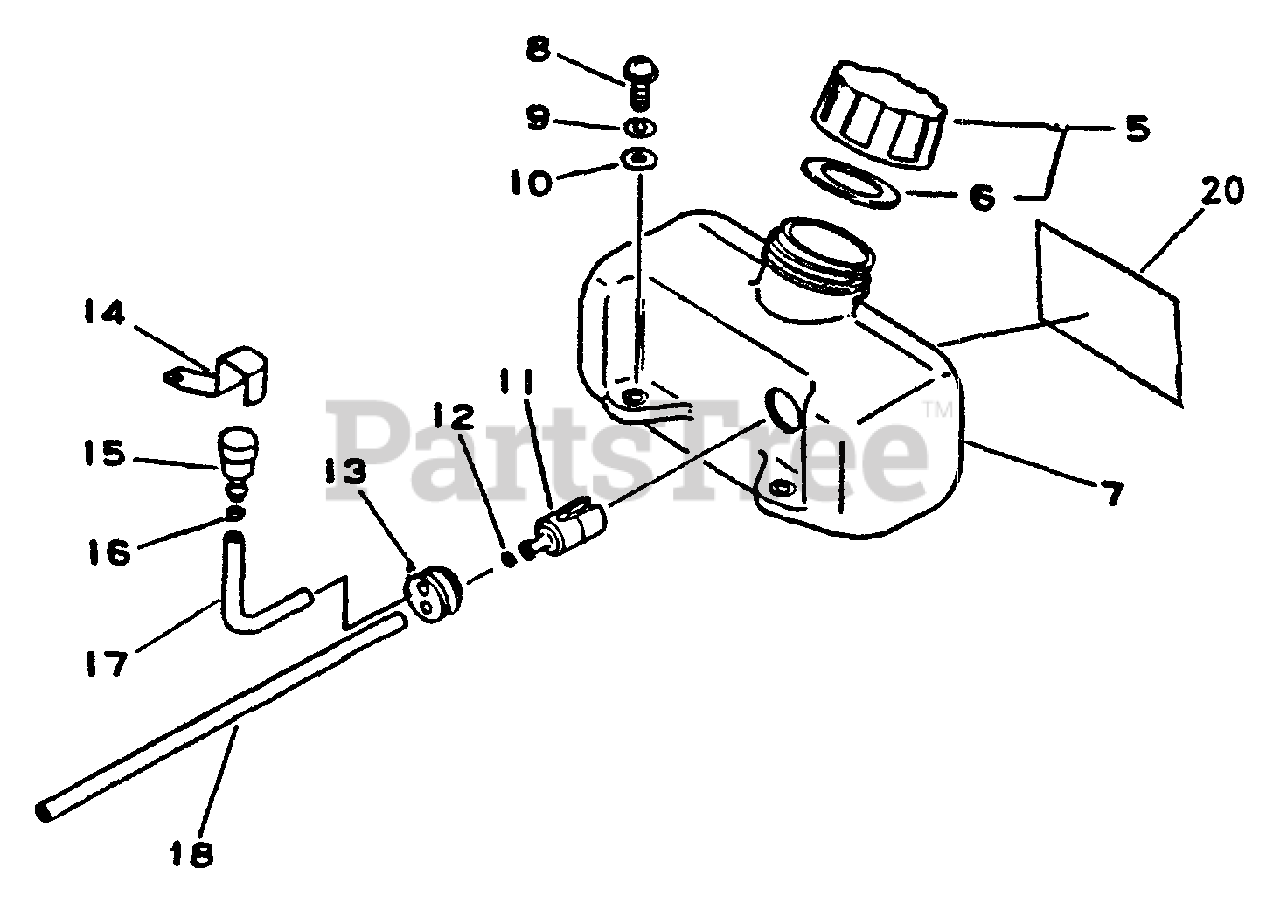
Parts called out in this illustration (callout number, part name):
5	CAP ASSY
6	GASKET, CAP
7	TANK, FUEL
8	SCREW - 5X16
9	LOCKWASHER - 5
10	WASHER - 5
11	FILTER, FUEL
12	CLIP - 6
13	GROMMET
15	VENT, FUEL TANK
16	RETAINER, PIPE
17	PIPE - 3X6X80 -- BLACK
18	PIPE - 3X5X195 -- BLACK
20	LABEL - CAUTION
